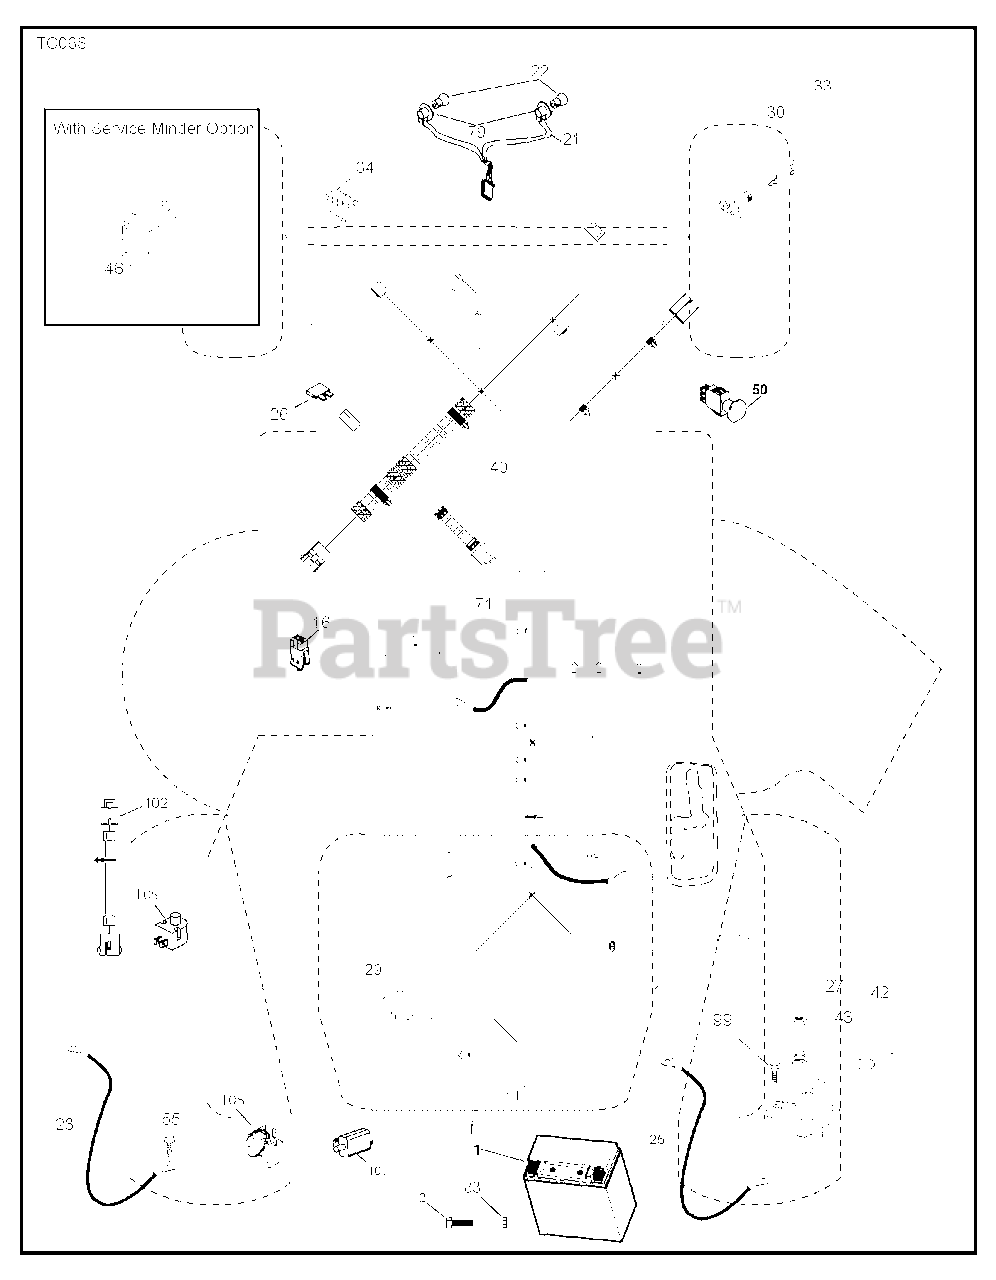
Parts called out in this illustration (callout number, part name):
1	BATTERY BATTERY 14AH 12V LEOC
2	SCREW.HEX.HEAD.CAP.M6 X1.12W
16	SWITCH INTERLOOK PUSH-IN
21	HARNESS.LIGHT W/4152J BULBS
25	CABLE.RED.8AWG.TCRD.GEN1
26	FUSE 20AMP
27	NUT
28	CABLE.BLACK.8AWG.TCRD.GEN1
29	SWITCH.SEAT.DELTA.OPC.
30	SWITCH.IGN.DELTA.W.LGH.ROS
33	KEY.CHAIN.BLISTER.PACK.GEN.USA
40	WIRING HARNESS
42	TERMINAL COVER
43	SOLENOID.W/BRASS.PLUNGER
46	RP GUAGE.SRVCMNDR.HRMTR.
50	RB PTO.SWITCH.8 TERMINAL.BLACK
55	SCREW 5/16"
71	HARNESS
79	BULB HOLDER ASM.
83	NUT NUT SQUARE
99	SCREW
102	HARNESS ASSY
105	REVERSE SWITCH
107	.WITCH.FULL BAGGER.INDICATOR
108	SWITCH.SNAPMOUNT.NC
